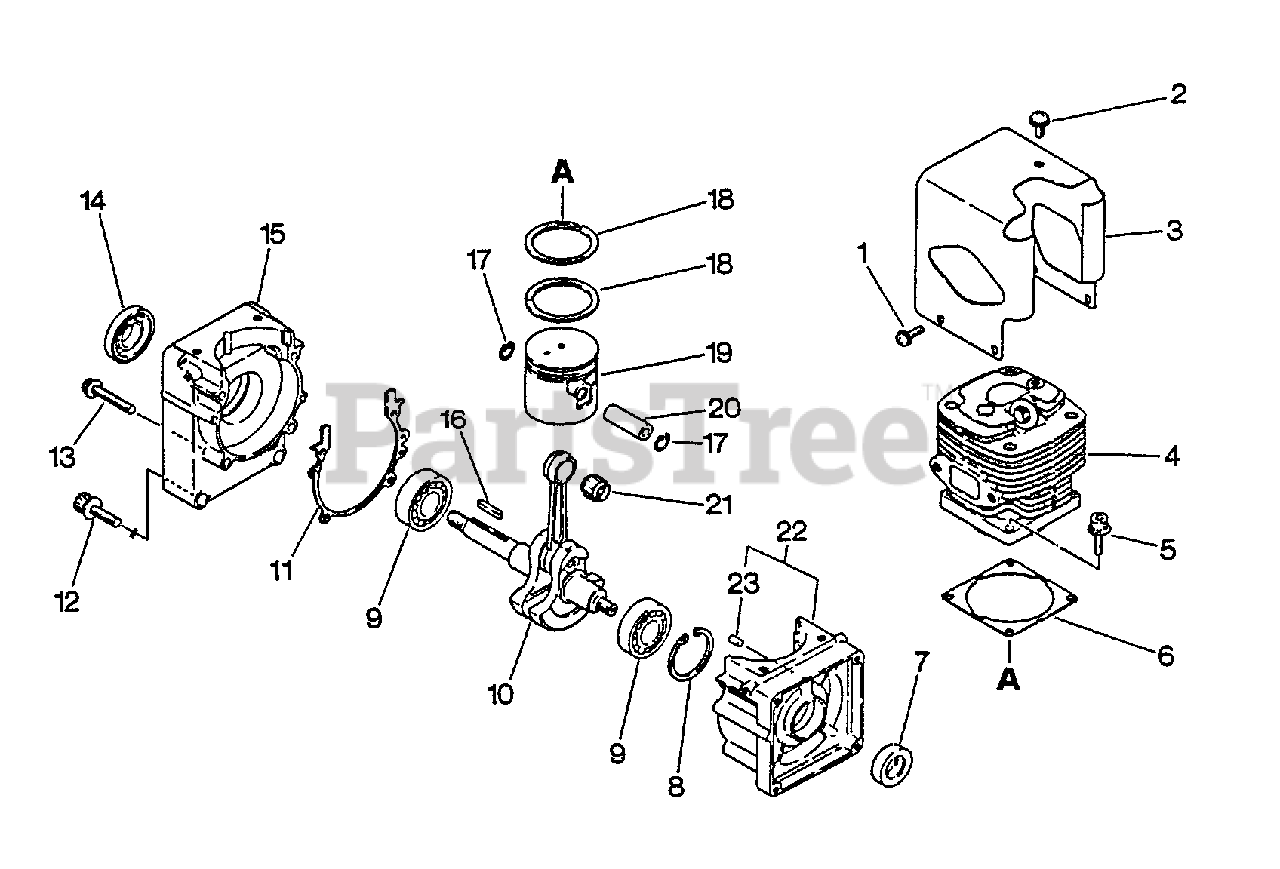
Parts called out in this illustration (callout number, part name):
1	SCREW - 4X10
2	SCREW - 5X10
3	COVER, CYLINDER - BLACK
4	CYLINDER
5	SCREW - 5X20
6	GASKET, CYLINDER
7	SEAL, OIL
8	RING, RETAINING - 35
9	BEARING, BALL - 6202
10	CRANKSHAFT ASSY
11	GASKET, CRANKCASE
12	SCREW - 6X20
13	SCREW - 5X30
14	SEAL, OIL
15	CRANKCASE KIT
17	RING, RETAINING - 8
18	RING, PISTON
19	PISTON
20	PIN, PISTON
21	BEARING, NEEDLE
22	CRANKCASE KIT
23	PIN - LOCATING
